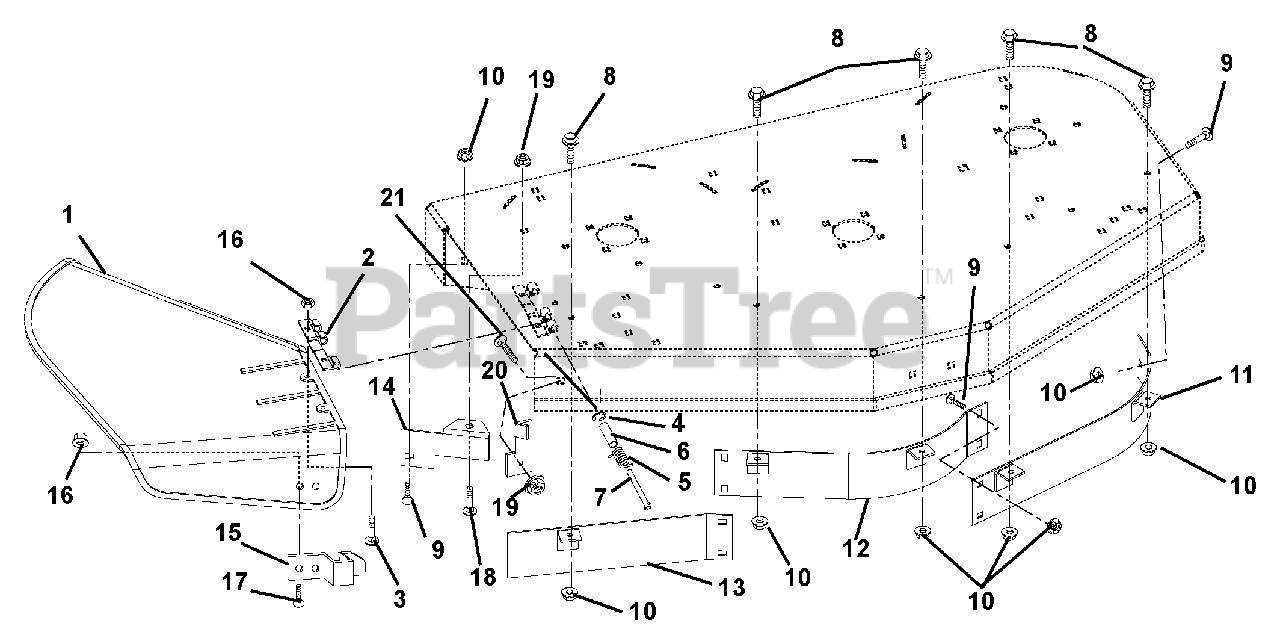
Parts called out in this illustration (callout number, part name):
1	Deflector, Chute
2	Hinge, Plate
3	Bolt, Round Head Square Neck .25-20 x .75 Grade 5
4	Ring, Retaining External .312 x .025
5	Spring, Torsion .095 x .50 x 1.00
6	Bushing, Sleeve
8	Bolt, Serrated Hex Flange Washer Head .31-18 x .75
9	Bolt, Round Head Square Neck .31-18 x .75
10	Nut-.312-18 Flange Nyloc
11	Weldment, Upper Left Baffle-40" (042, 044)
11	Weldment, Upper Left Baffle-44" (046)
11	Weldment, Upper Left Baffle-48" (048)
11	Weldment, Upper Left Baffle-52" (050)
12	Weldment, Upper Center Baffle-40" (042, 044)
12	Weldment, Upper Center Baffle-44" (046)
12	Weldment, Upper Center Baffle-48" (048)
12	Weldment, Upper Center Baffle-52" (050)
13	Weldment, Upper Right Baffle-40" (042, 044)
13	Weldment, Upper Right Baffle-44" (046)
13	Weldment, Upper Right Baffle-48" (048)
13	Weldment, Upper Right Baffle-52" (050)
14	Deflector, 40" (042, 044)
14	Deflector, 44"/48" (046, 048)
14	Deflector, 52" (050)
15	Flat Spring
16	Nut, Locking Top Flange .25-20
17	Bolt, Round Head Square Neck .25-20 x .50 Grade 5
18	Bolt, Round Head Square Neck .38-16 x 1.00 Grade 5
19	Nut, Flange Nyloc .375-18
20	Bracket, Chute Lock
21	Bolt, Round Head Square Neck .38-16 x 1.50
